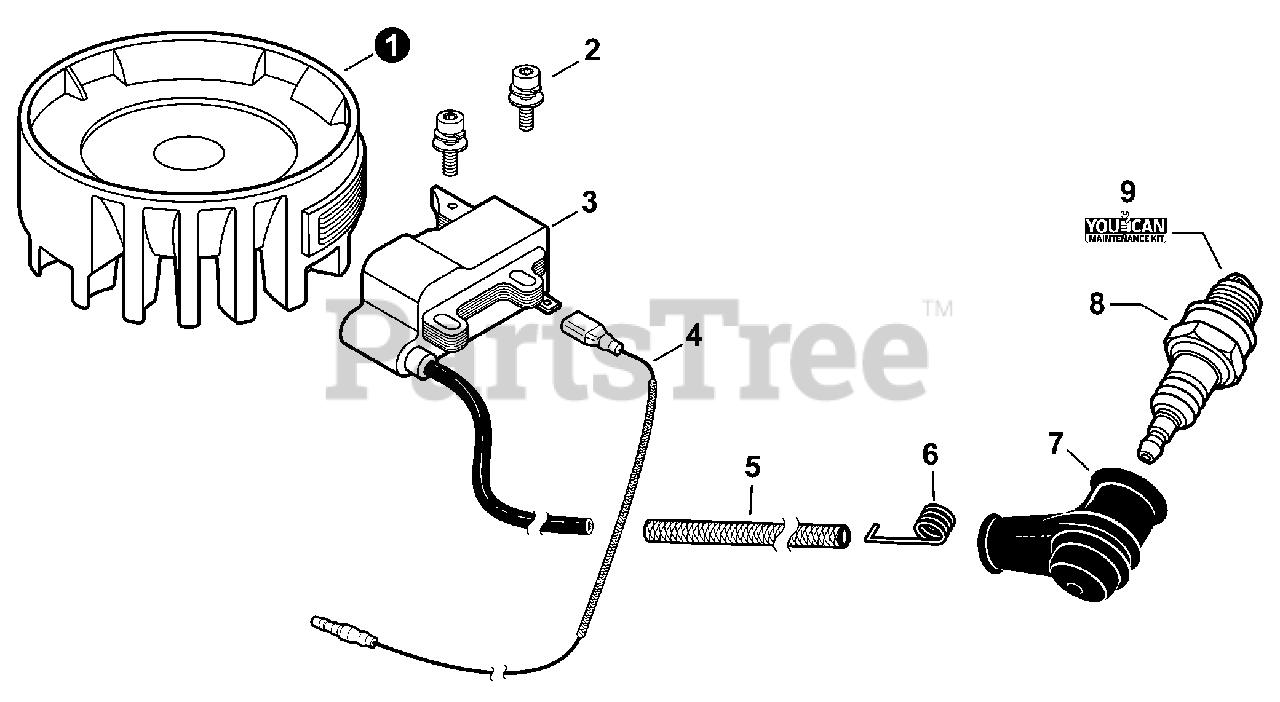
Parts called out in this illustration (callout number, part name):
1	FLYWHEEL
2	BOLT 4×20
3	COIL, IGNITION
4	LEAD - IGNITION
5	TUBE, INSULATOR 7×8.6×55
6	TERMINAL, SPARK PLUG
7	CAP, SPARK PLUG
8	SPARK PLUG - BPMR8Y
9	TUNE-UP KIT - YOUCAN™
